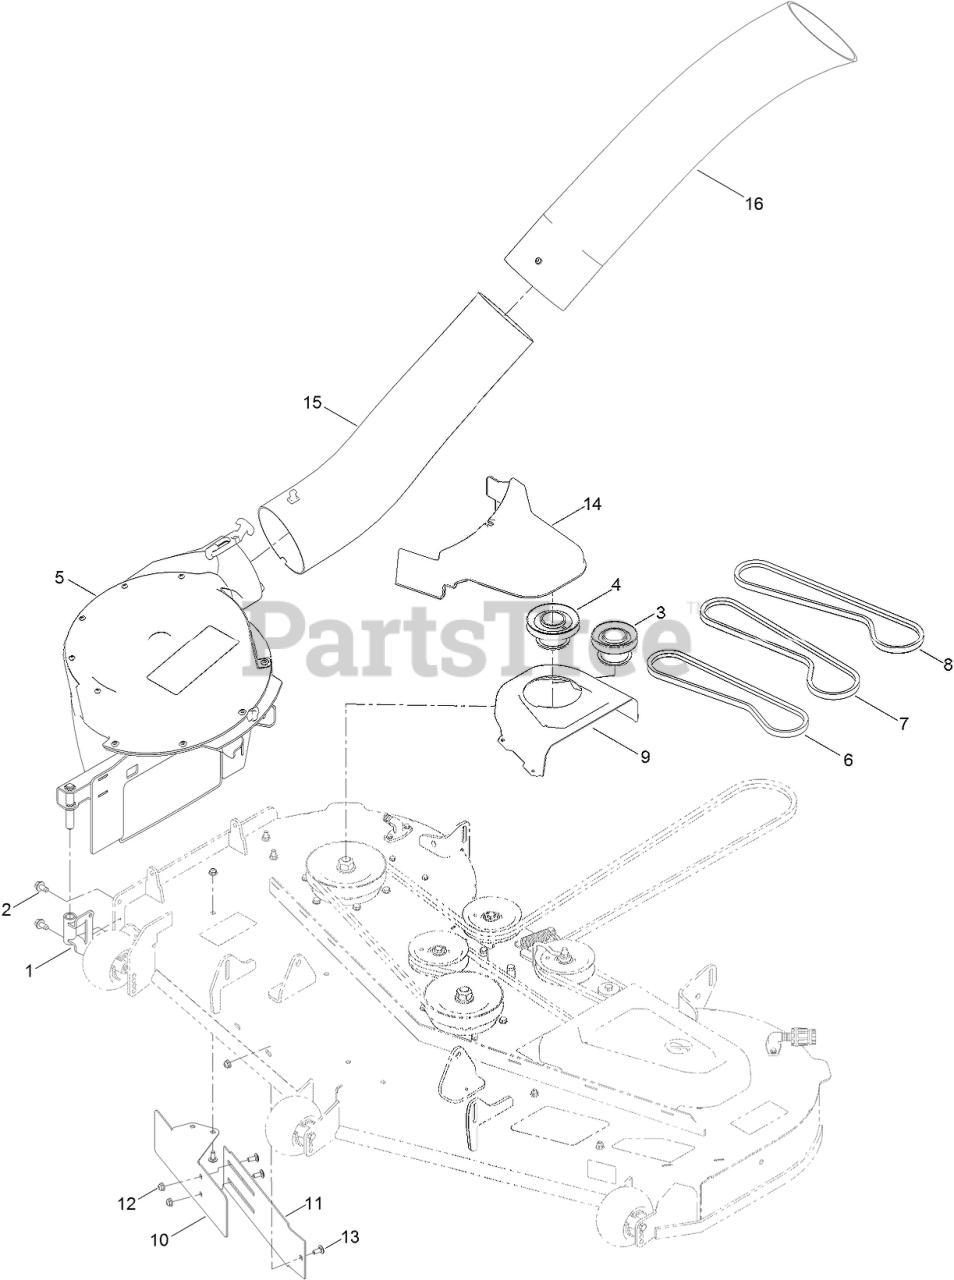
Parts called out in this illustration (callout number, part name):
1	PIVOT-BLOWER
2	SCREW-HWH
3	PULLEY-BAGGER
4	PULLEY-BAGGER
5	Blower Housing Assembly
6	BELT-V
7	BELT-V
8	BELT-V
9	COVER-BELT, RH
10	BAFFLE-OUTER
11	BAFFLE-INNER
12	NUT-HF
13	BOLT-CARR
14	COVER-BAGGER, POWERED
15	Lower Tube ASM
16	Upper Tube ASM
